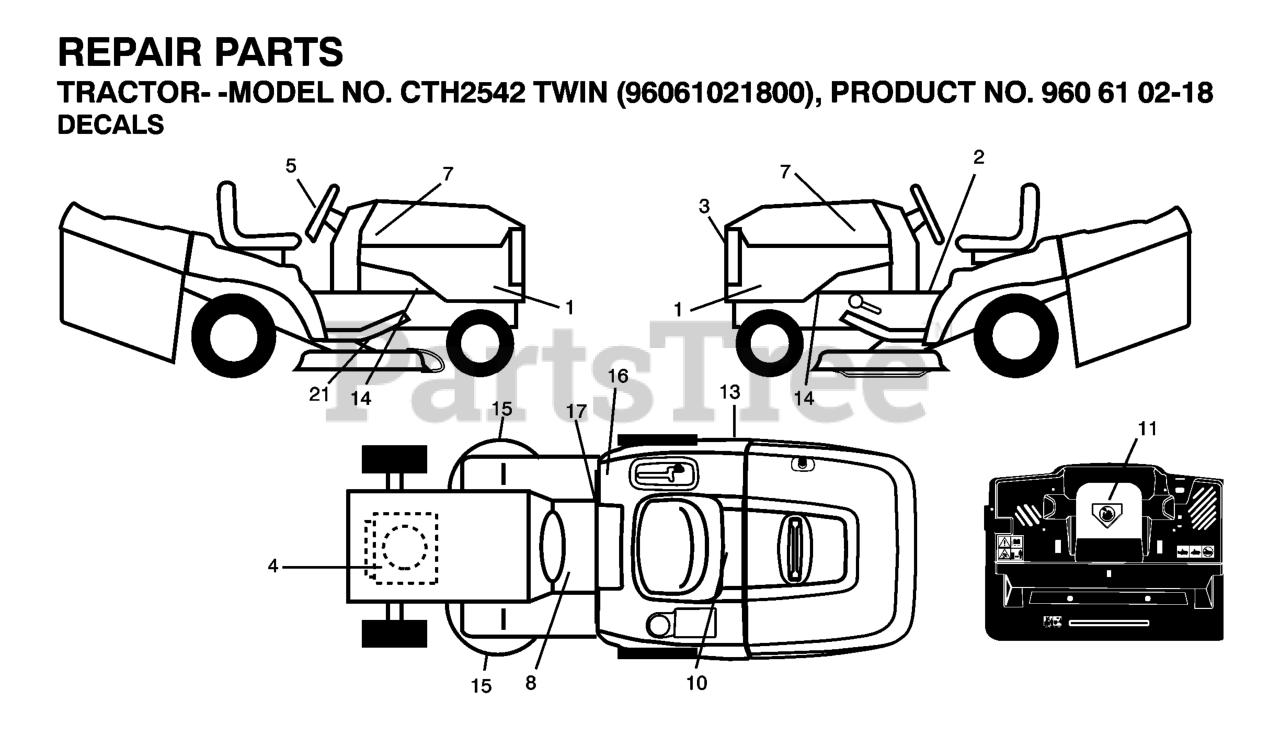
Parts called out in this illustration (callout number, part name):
2	LABEL
3	DECAL.HOOD.TOP.INSERT.
4	DECAL
5	DECAL.WHEEL.STRG.LGN.H
7	DECAL.HOOD.NAMELOGO.HUSQ
8	DECAL
10	DECAL BTRY SYMBOLS
11	DECAL.INTERNATIONL.CUTFINGER
13	DECAL 80 DBA
16	DECAL
17	DECAL PARK BRAKE
